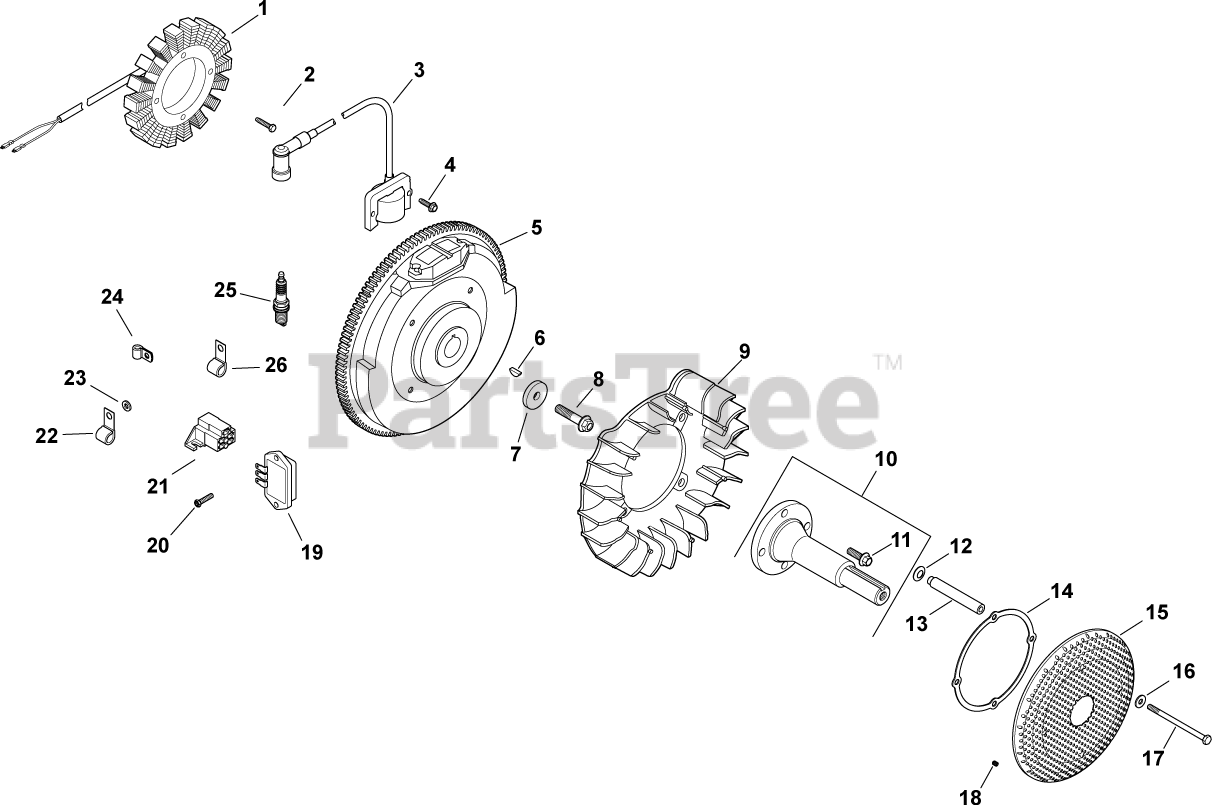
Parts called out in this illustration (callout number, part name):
1	KIT, 15 / 20 AMP STATOR
2	SCREW, M5X0.8X25 - (#25086402S)
3	KIT, MODULE IGNTN (CDI FIXED)
4	SCREW, FLG THD FRM M5X.8X20-(#25086399S)
5	FLYWHEEL, PAINTED-USE 24 025 59-S
6	KEY, 3/16" X 5/8"
7	WASHER, FLAT 13/32"
8	SCREW, FLG M10X1.5X45 - (#25086361S)
9	FAN USE 24 755 253-S
10	SHAFT, FRONT DRIVE
11	SCREW, FLG M8X1.25X25
12	WASHER, SPRING 10 MM
14	RING, SUPPORT USE 25 141 08-S
15	SCREEN, GRASS
16	WASHER, FLAT 1/4" (O.D. 5/8")
17	SCREW, CAP M6X1.0X99.5
18	SCREW, SKT SET #10-24X1/4"
19	REG/RECT-15 AMP (KM)-USE 41 403 10-S
20	SCREW, FLG SEMS M4X.7X25
21	CONNECTOR
22	CLIP, CABLE
23	WASHER, FLAT 1/4" (O.D. 1/2")
24	CLIP, TUBE & WIRING (KM)
25	PLUG, SPARK (PRO SERIES)
26	CLIP, CABLE - USE 24 154 10-S
